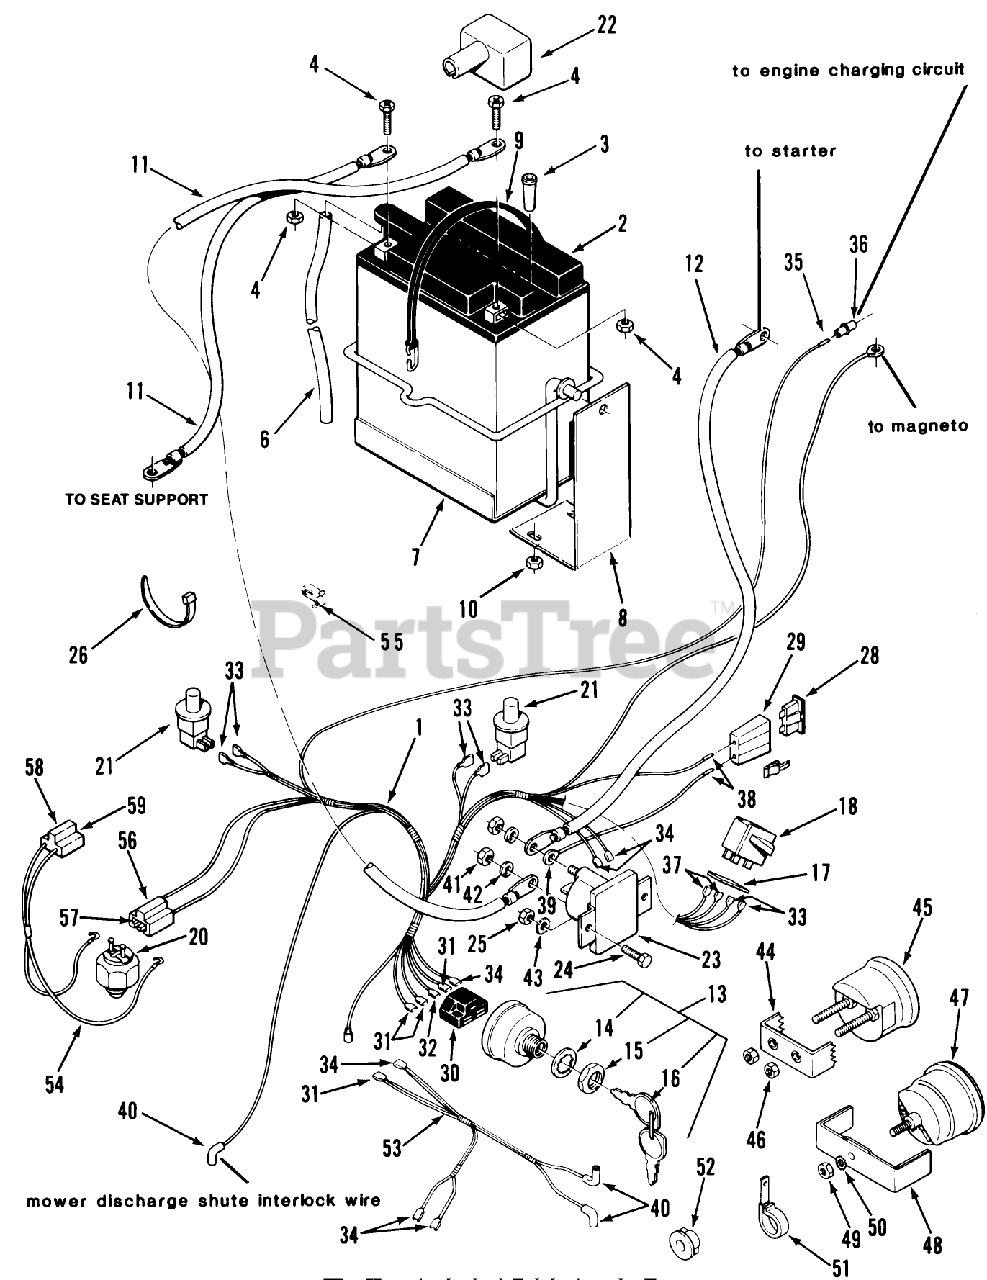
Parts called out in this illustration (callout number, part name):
7	BATTERY TRAY *B
8	BRACKET *B
12	WIRE ASM
20	SWITCH (N.C.-TRANS)
28	FUSE-BLADE, 15 AMP
32	TERMINAL-TAB RCPT
33	Terminal
37	Wire Terminal (Part of 1)
44	CLAMP MOUNTING
46	HEX NUT 10-32 E.S. + + USE 3296-21 + +
51	CLAMP
54	ASSY WIRING HARNESS
56	WHEEL ASM
57	Connector Part of 5
58	CONNECTOR BODY *B
59	TERMINAL-TAB RCPT
